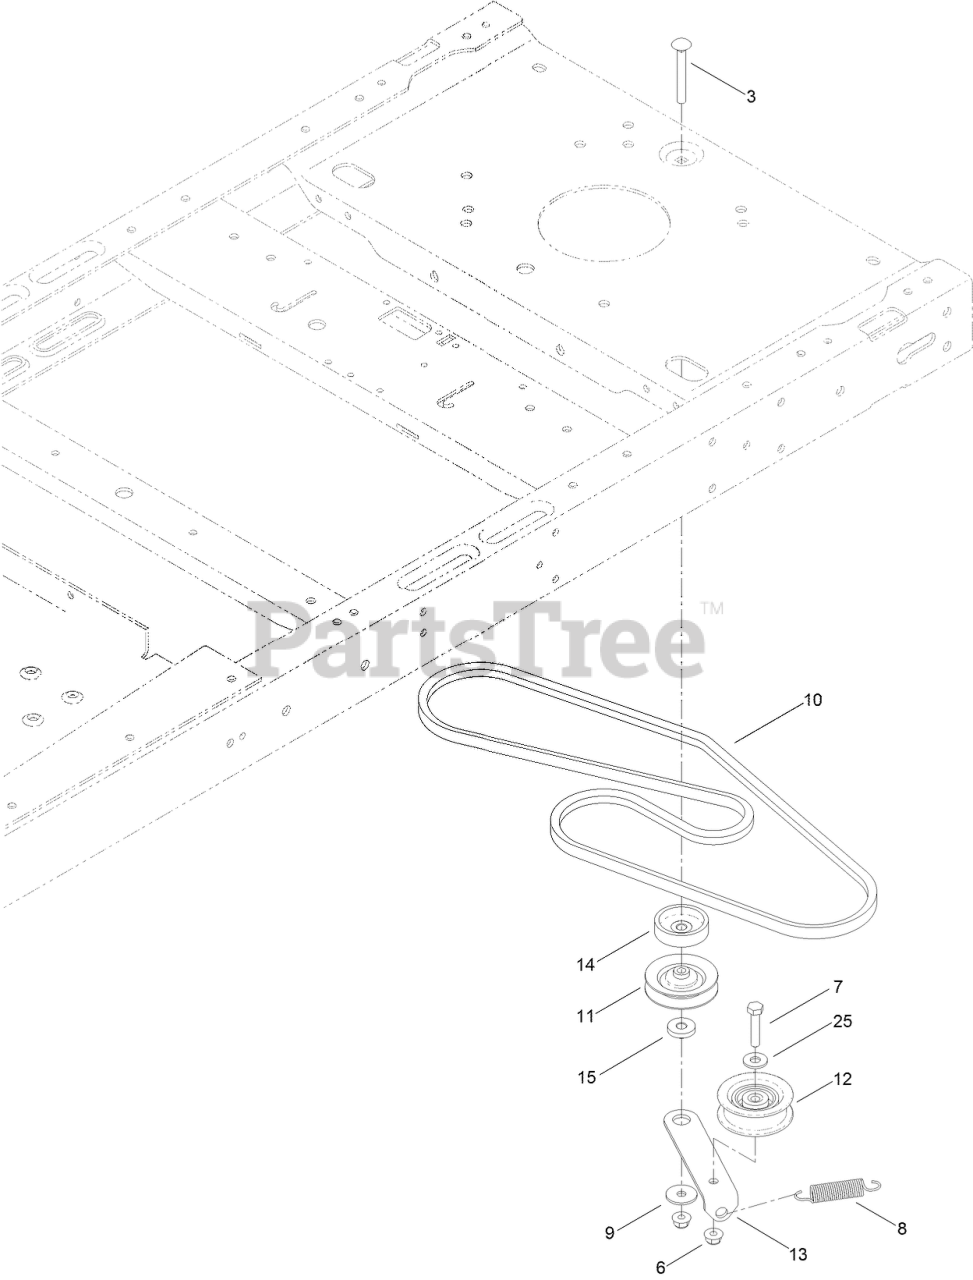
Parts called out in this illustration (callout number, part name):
3	SCREW-CARR
6	NUT-HF, NI
7	SCREW-HH
8	SPRING-RETURN, PEDAL
9	WASHER-PIVOT
10	V-BELT
11	PULLEY-IDLER
12	PULLEY-IDLER
13	ARM-IDLER
14	SPACER
15	SPACER-ARM, IDLER
25	WASHER-FLAT
